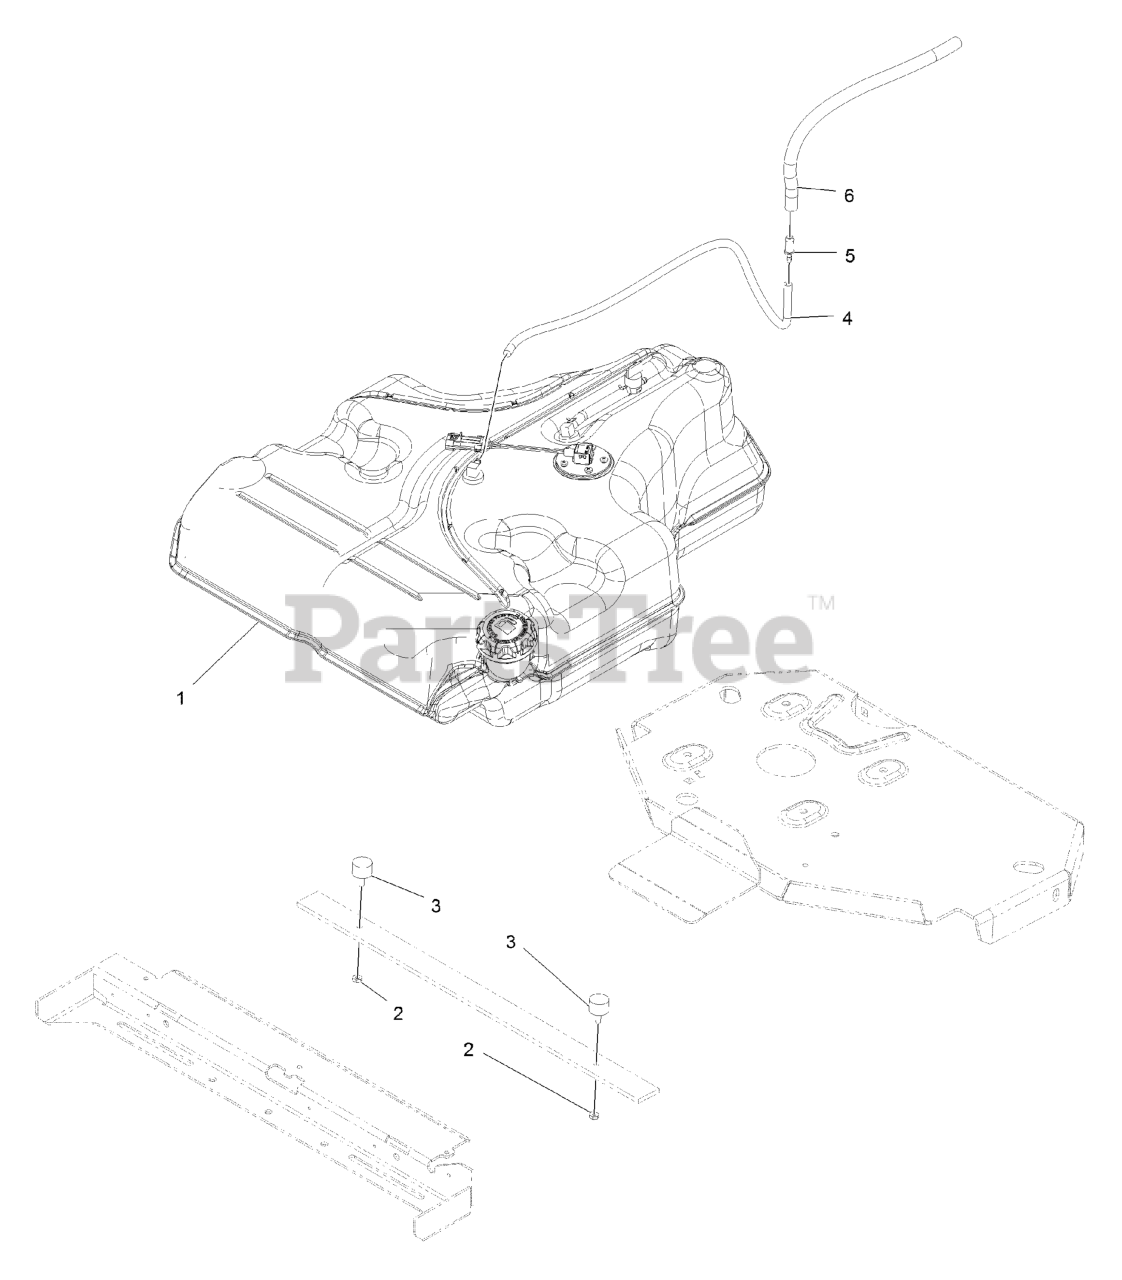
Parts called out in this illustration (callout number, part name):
2	NUT-JAM
4	HOSE-FUEL
5	FITTING-STRAIGHT
6	HOSE-FUEL
